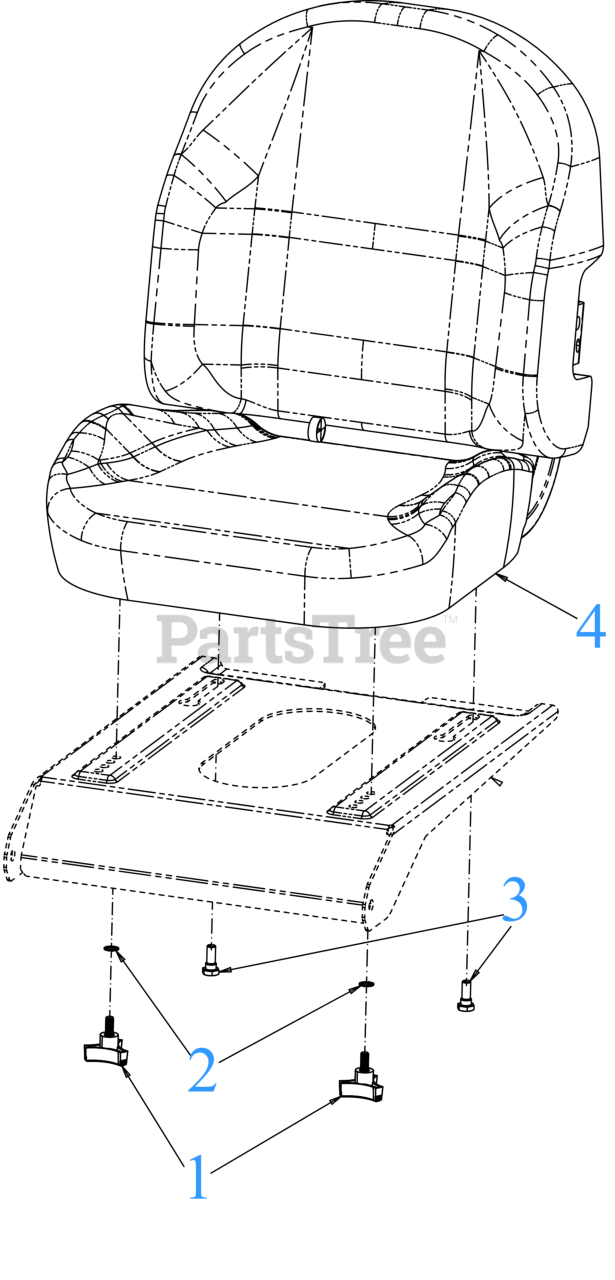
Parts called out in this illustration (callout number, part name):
1	3 PRONG KNOB 5/16-18
3	SHOULDER SCREW .437
4	SEAT BACK REPLACEMENT COVER
4	SEAT CUSHION REPLACEMENT COVER
4	DOME COVER SEAT SWITCH
4	SEAT SWITCH (NC/NO)
